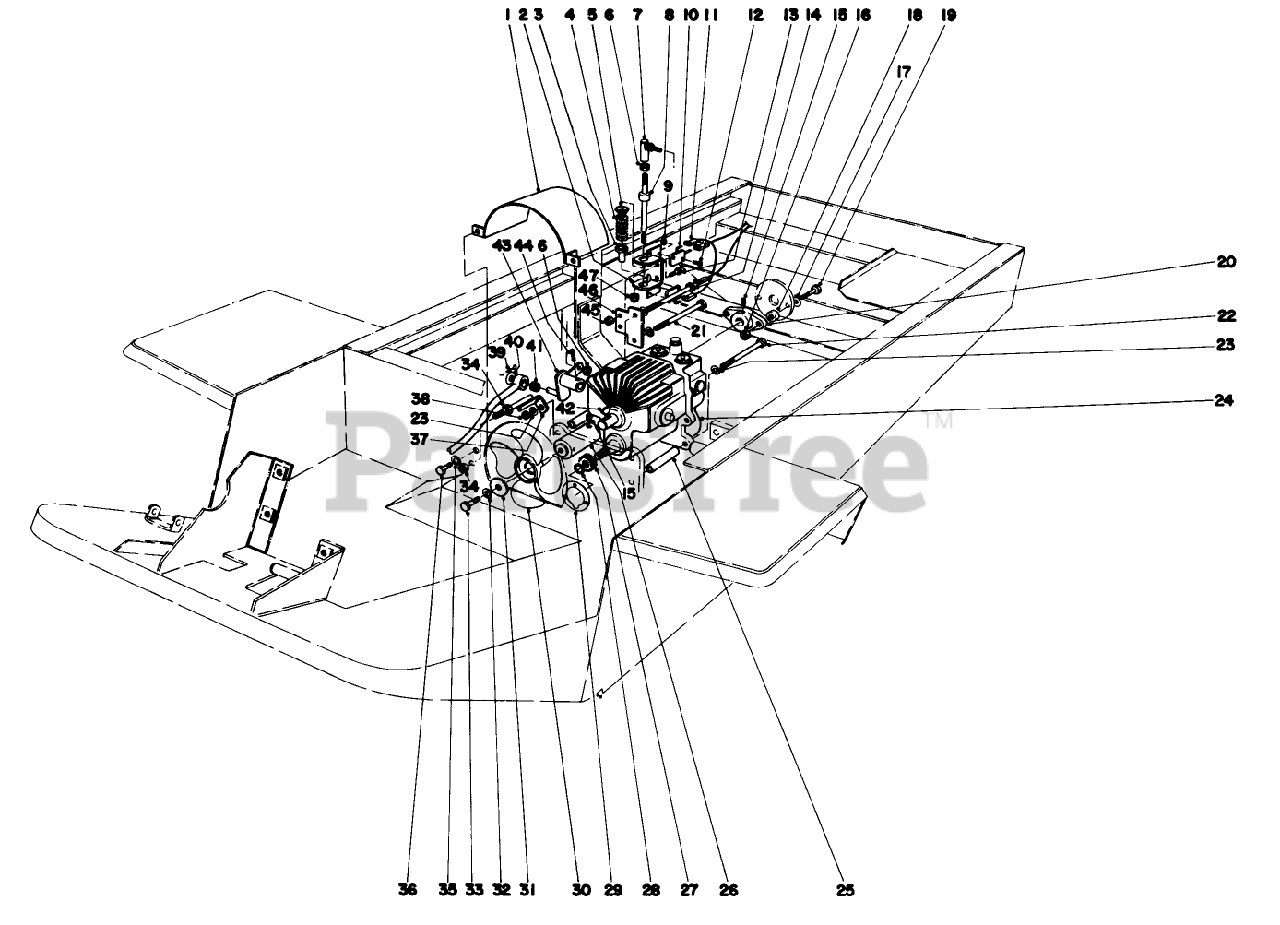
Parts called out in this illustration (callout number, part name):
1	Fan Shroud
2	EQUALIZER BRKT WA
3	Retain-Spring Bottom
4	COMPRESSION SPRING
5	SPRING TOP RETAINER
6	NUT-HJ
7	BALL JOINT
8	EQUALIZER BAR WA
9	NUT-LOCK, NI
10	MICRO SWITCH
11	TRAC SWITCH WIRE
12	4-40 X 3/4 MS
13	SCREW-HH
14	SCREW-HH
15	SCREW-SET, HSH
16	NUT-HEX
17	WASHER-FLAT
18	SPACER-COUPLING, RUBBER
19	SCREW-HH
20	HUB-PUMP
21	SCREW-HH
22	SCREW-HH
23	WASHER-LOCK
24	Transmission
25	SPACER-MOUNTING
26	Hub & Plug
27	Gear
28	Ring-Snap
29	GASKET-TRANSMISSION
31	WASHER
32	WASHER-LOCK
33	SCREW-HH
34	NUT-JAM
35	WASHER-LOCK
36	SCREW-HH
37	Axle Support
38	NUT-HEX
39	PIN-COTTER
40	WASHER-FLAT
41	BUSHING-RUBBER
42	KEY-WOODRUFF
43	PUMP LEVER WA
44	PIN-SPRING
45	NUT-LOCK, NI
46	Support Equalizer
47	NUT-LOCK
